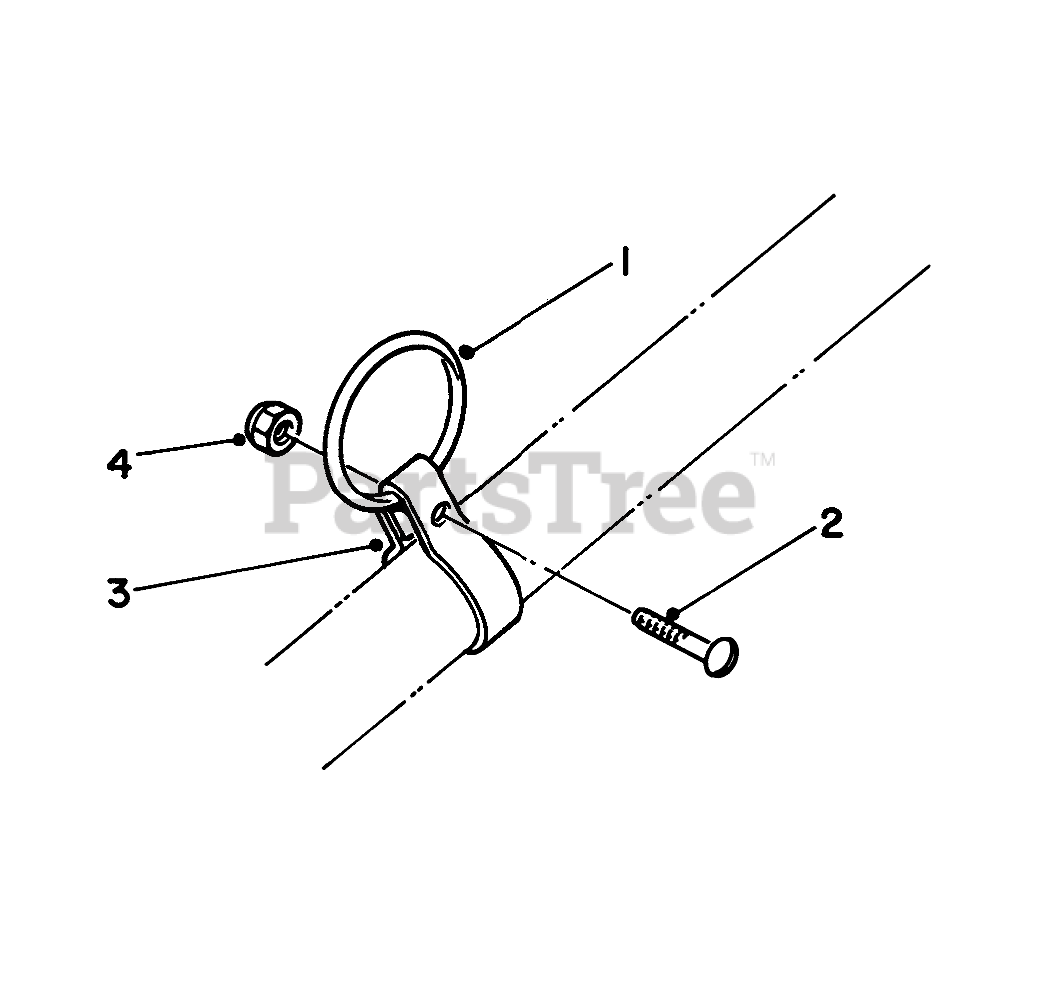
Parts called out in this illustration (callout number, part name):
1	Ring
2	SCREW-SRH
3	Clamp
4	NUT-LOCK, NI
